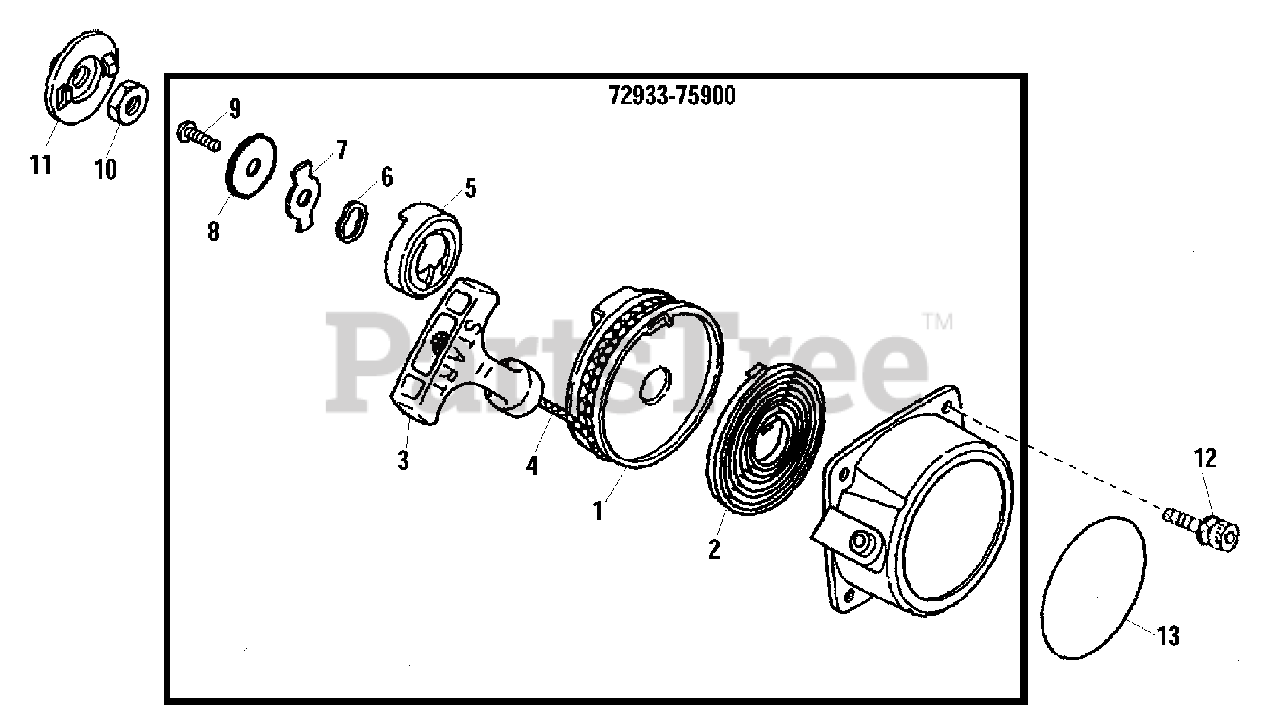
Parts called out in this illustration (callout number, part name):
1	REEL, ROPE
2	SPRING, REWIND
3	GRIP, STARTER
4	ROPE, STARTER
5	PAWL, STARTER
6	WASHER - SPRING
7	RETAINER
8	WASHER - 5
9	SCREW - 5
10	NUT - 8
11	PAWL
12	SCREW - 4X12
13	LABEL - SHINDAIWA PROFESSIONAL
72933-75900	STARTER ASSY
